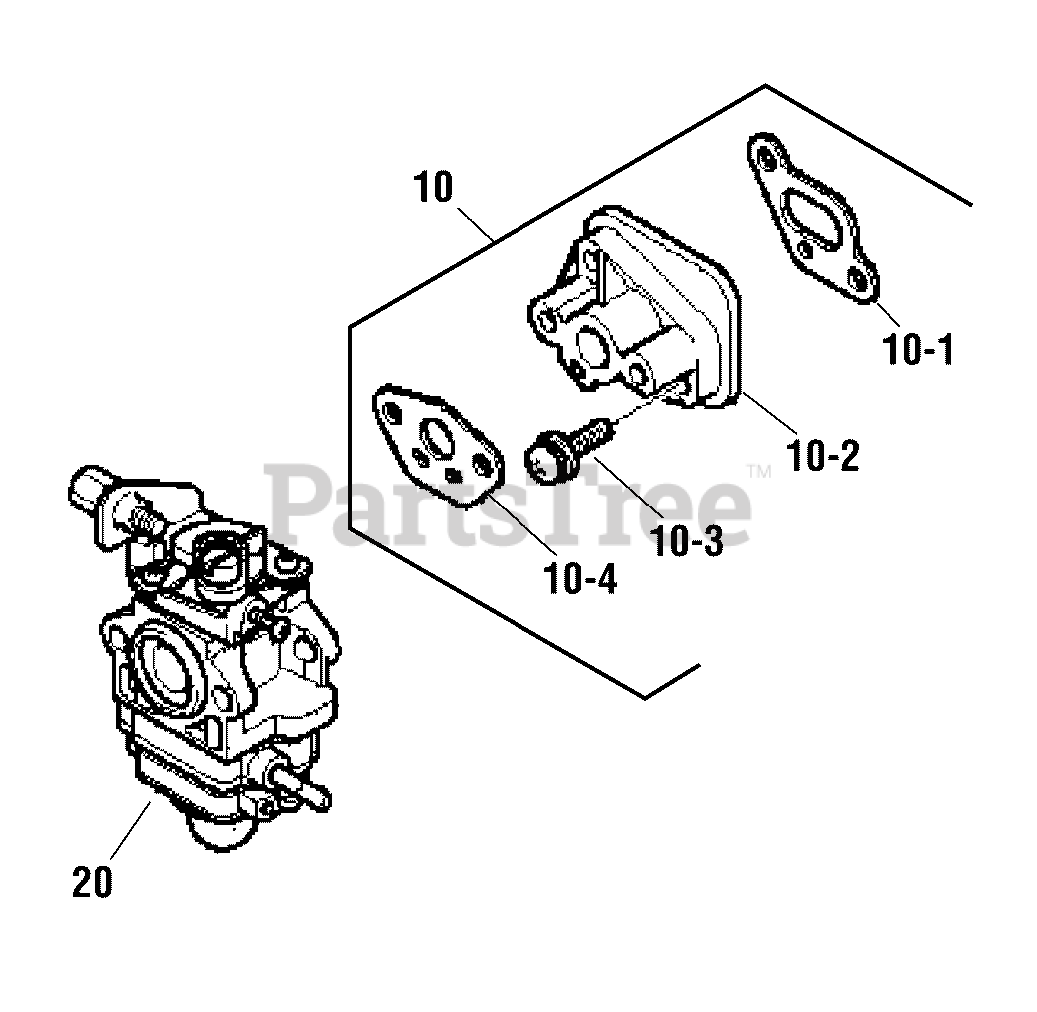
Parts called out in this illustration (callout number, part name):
10	INTAKE MANIFOLD ASSEMBLY
10-1	GASKET, Insulator
10-2	INSULATOR
10-3	SCREW & WASHER
10-4	GASKET, Carburetor
20	CARBURETOR
